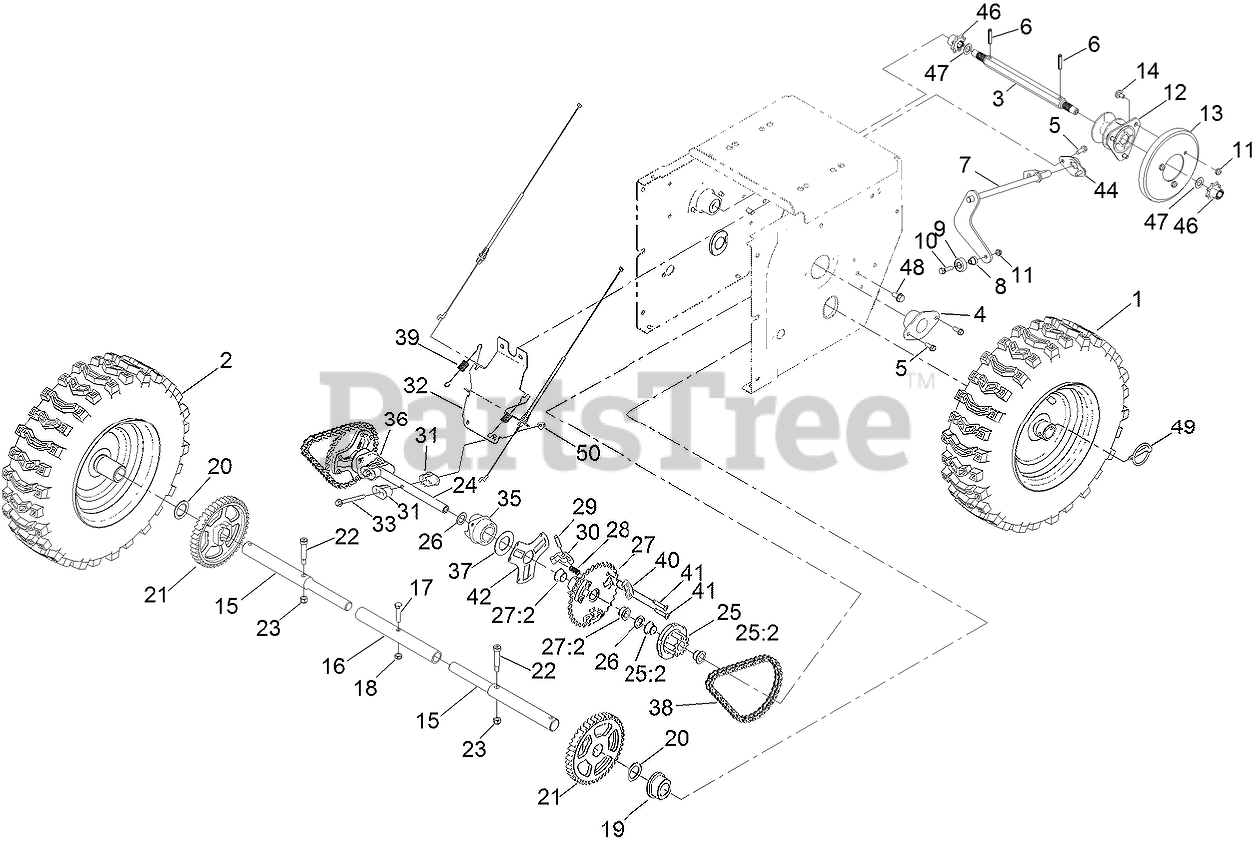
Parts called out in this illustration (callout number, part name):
1	LH WHEEL AND TIRE ASM
2	RH WHEEL AND TIRE ASM
3	SHAFT-HEX
4	RETAINER-BEARING
5	SCREW-HWH
6	PIN-ROLL, SLOTTED
7	ROD-SHIFT
8	SPACER-PLATE, SHIFT
9	BEARING-BALL
10	SCREW-HWHTF
11	NUT-HEX
12	TRUNNION
13	WHEEL-FRICTION
14	SCREW-SHOULDER
16	TUBE-AXLE
17	SCREW-HH
18	NUT-HEX
19	BUSHING-AXLE
20	WASHER-THRUST
21	GEAR-AXLE
22	BOLT-SHOULDER, HSH
23	NUT-HEX
24	SHAFT-INTERMEDIATE
25	11T GEAR ASM
25:2	BUSHING-FLANGE
26	WASHER-FLAT
27	32T SPROCKET ASM
27:2	BUSHING-FLANGE
28	SPRING-COMPRESSION
29	PIN-DOWEL
30	PAWL-CLUTCH
31	GUIDE-COLLAR
32	BRACE-SHIFT, COLLAR
33	SCREW-HHF
35	COLLAR-SHIFT, LH
36	COLLAR-SHIFT, RH
37	WASHER-THRUST
38	CHAIN-ROLLER
39	SPRING-EXTENSION
40	SUPPORT-PAWL
41	SCREW-BHCS
42	RETAINER-PAWL, PIN
44	RETAINER-ROD, SHIFT
46	GEAR-PINION, 8 TOOTH
47	WASHER-PLAIN
48	SCREW-HWHTF
49	PIN-KLIK
50	NUT-FLANGE, NI
